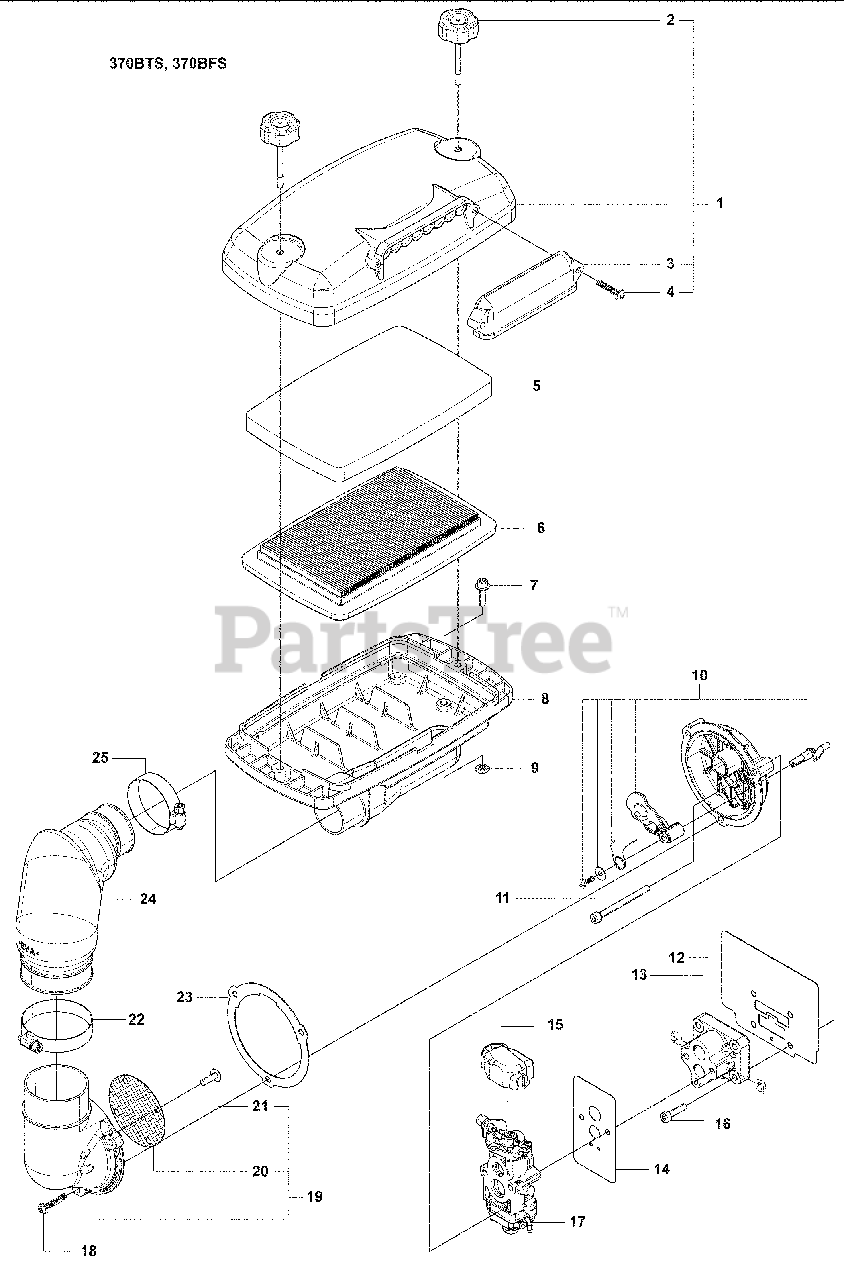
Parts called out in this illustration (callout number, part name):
1	Cover
4	Screw
5	Air Filter Element
6	Air Filter Element
7	Bolt
10	Cup Assembly
11	Bolt
12	Gasket
13	Insulator
14	Gasket
15	Cover
16	Bolt
17	Carburetor
18	Screw
19	Cup Cover Assembly
21	Screw
22	Clamp, F64
23	Gasket
24	HOSE
25	CLAMP(F51)
